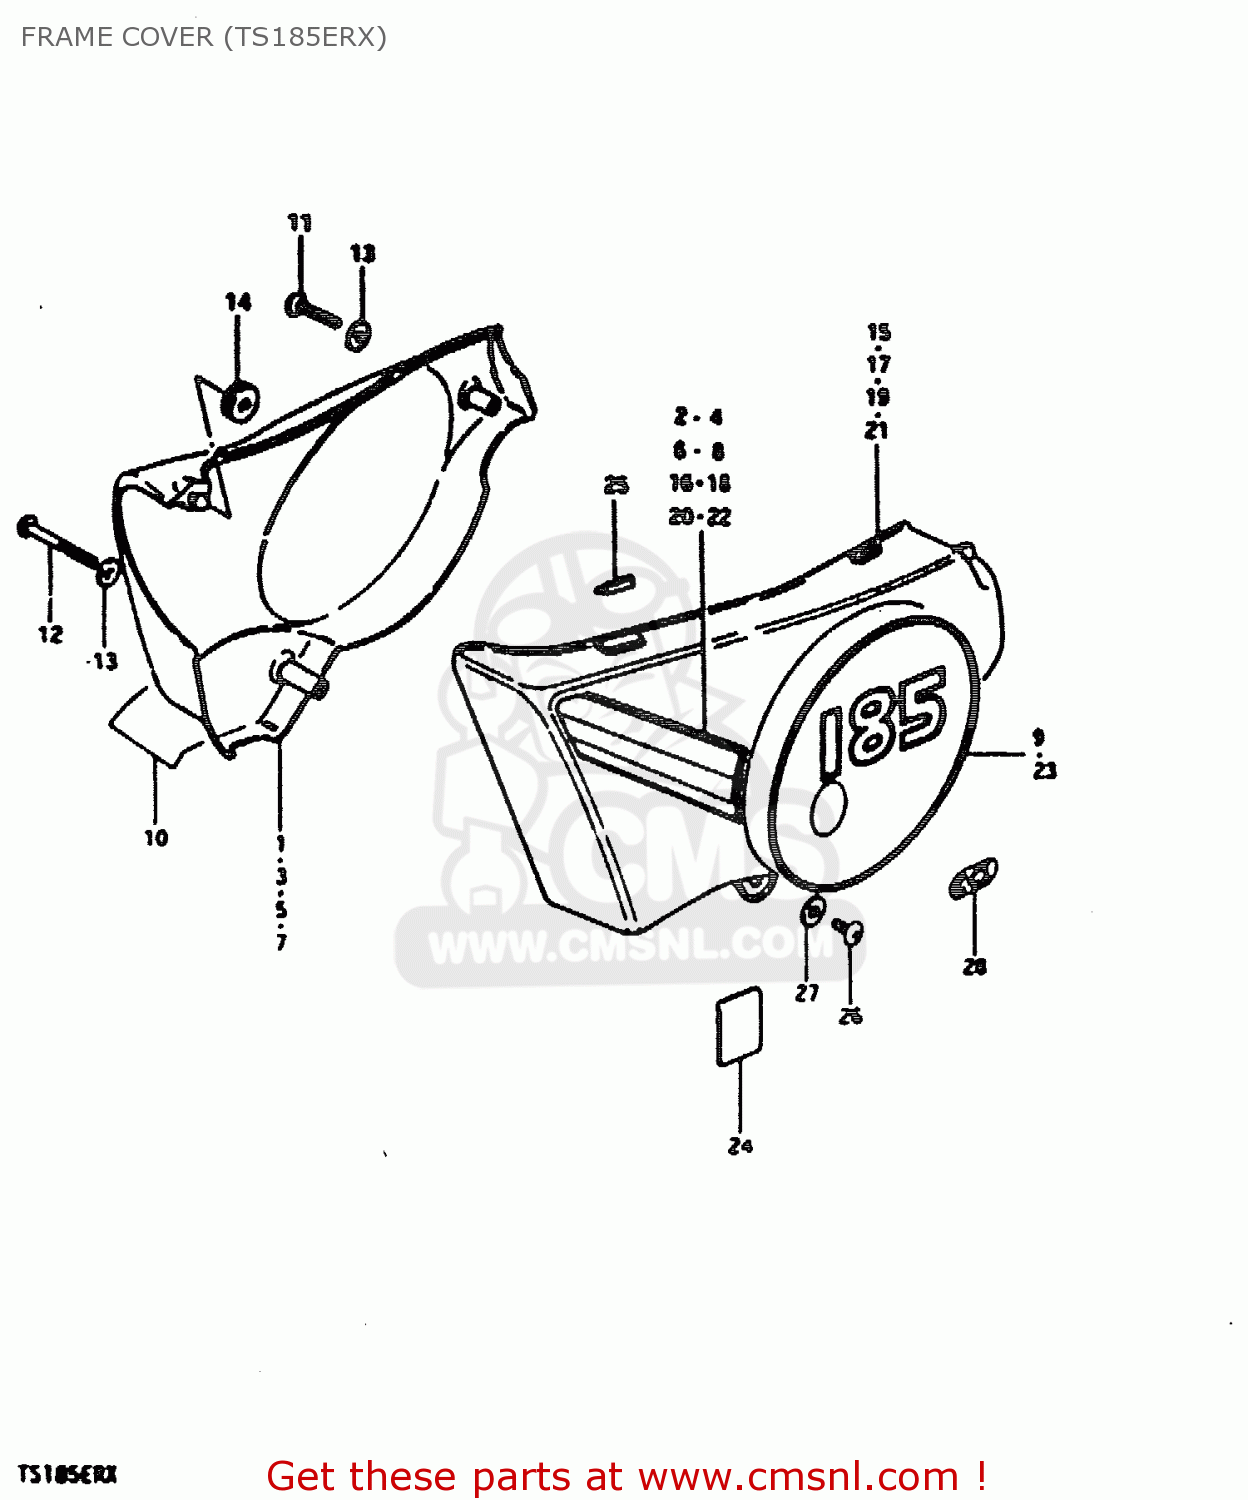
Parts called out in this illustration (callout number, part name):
1	COVER,FRAME,RIGHT
2	TAPE, RH
3	COVER, FRAME RH (YELLOW)
4	TAPE, RH
5	COVER, FRAME RH (RED)
6	TAPE, RH
7	COVER, FRAME RH (WHITE)
8	TAPE, RH
9	EMBLEM, "185" RH (WHITE)
10	EMBLEM,FRAME COVER,RIGHT
11	SCREW
12	SCREW
13	WASHER
14	CUSHION
15	COVER,FRAME,LEFT
16	TAPE, LH
17	COVER, FRAME LH (YELLOW)
18	TAPE, LH
19	COVER, FRAME LH
20	TAPE, LH
21	COVER, FRAME LH (WHITE)
22	TAPE, LH
23	EMBLEM, "185" LH (WHITE)
24	PROTECTOR(170X95X3.0)
25	CUSHION,FRAME COVER
26	SCREW
27	WASHER
28	EMBLEM,CCIS
